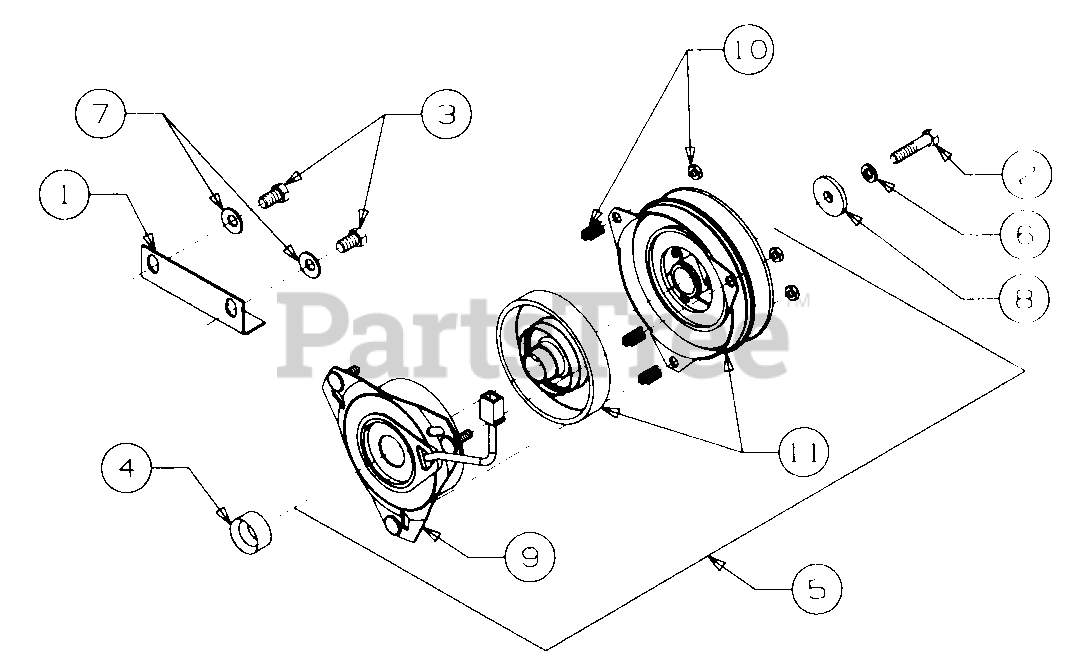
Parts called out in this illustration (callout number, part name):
3	Screw, Hex Cap, 7/16-14 x .75 Lg GR5
4	Spacer
5	Clutch Assy, PTO
6	Washer, Lock, 3/8
7	Washer, Bell, .45 x 1.0 x .062 Thk
8	Washer, Flat, .445 x 1.5 x .1 72 Thk Hdn
9	Field Assy
10	Mounting Accessories
11	Kit, Armature and Rotor
